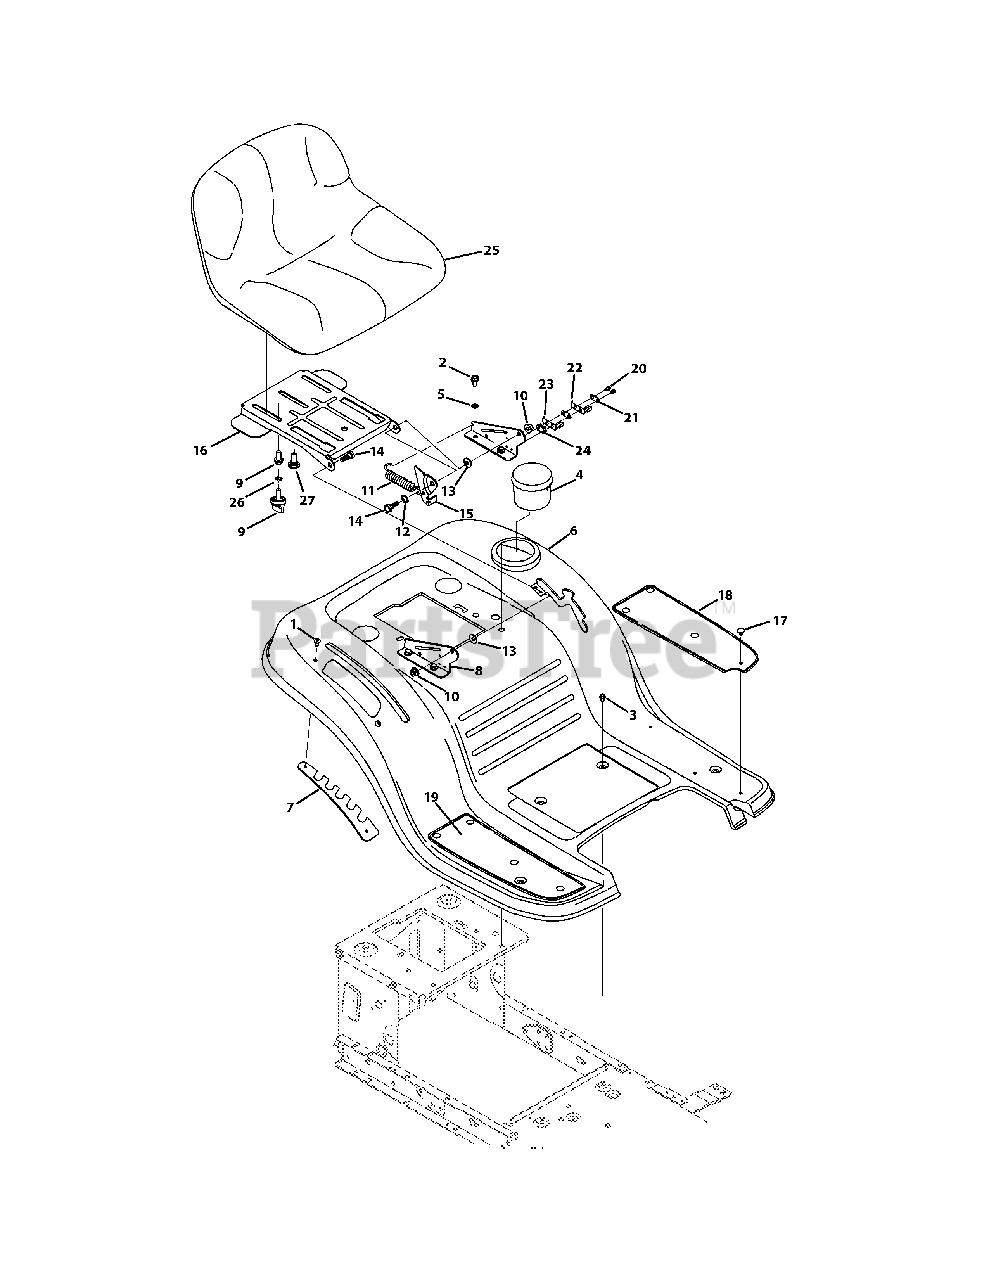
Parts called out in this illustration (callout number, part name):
1	Screw, 1/4-20 x .500
2	Screw, 5/16-18 x .750
3	Screw Pan Torx Head, 1/4-20 x .500
4	Cup Holder
5	Loack Washer, 5/16
6	Fender - Black
6	Fender - Green
8	Seat Mount Bracket
9	Hex Flange, 3/8-16 x .875
9	Knob
10	Flangelock Nut, 5/16-18
11	Extension Spring
12	Flat Washer, .510x .750 x .033
13	Bell Washer, .340 x .872 x .060
14	Shoulder Screw, 5/16-18 x .437 x .268
15	Lift Seat Bracket
16	Pivot Seat Manual Adjust Bracket
17	Ratchet Clip, .250 x .500
18	Foot Pad, LH
18	Foot Pad, Abrasive, LH
19	Foot Pad, RH
19	Foot Pad, Abrasive, RH
20	Screw, 8-18 x .500
21	Insulator Plate
22	Outer Seat SPring
23	Inner Seat Spring
24	Insulator Boss Plate
25	Low Back Seat
25	Medium Back Seat
26	Lock Washer
27	Screw., Shldr., .625 x .145 x 3/8-16
